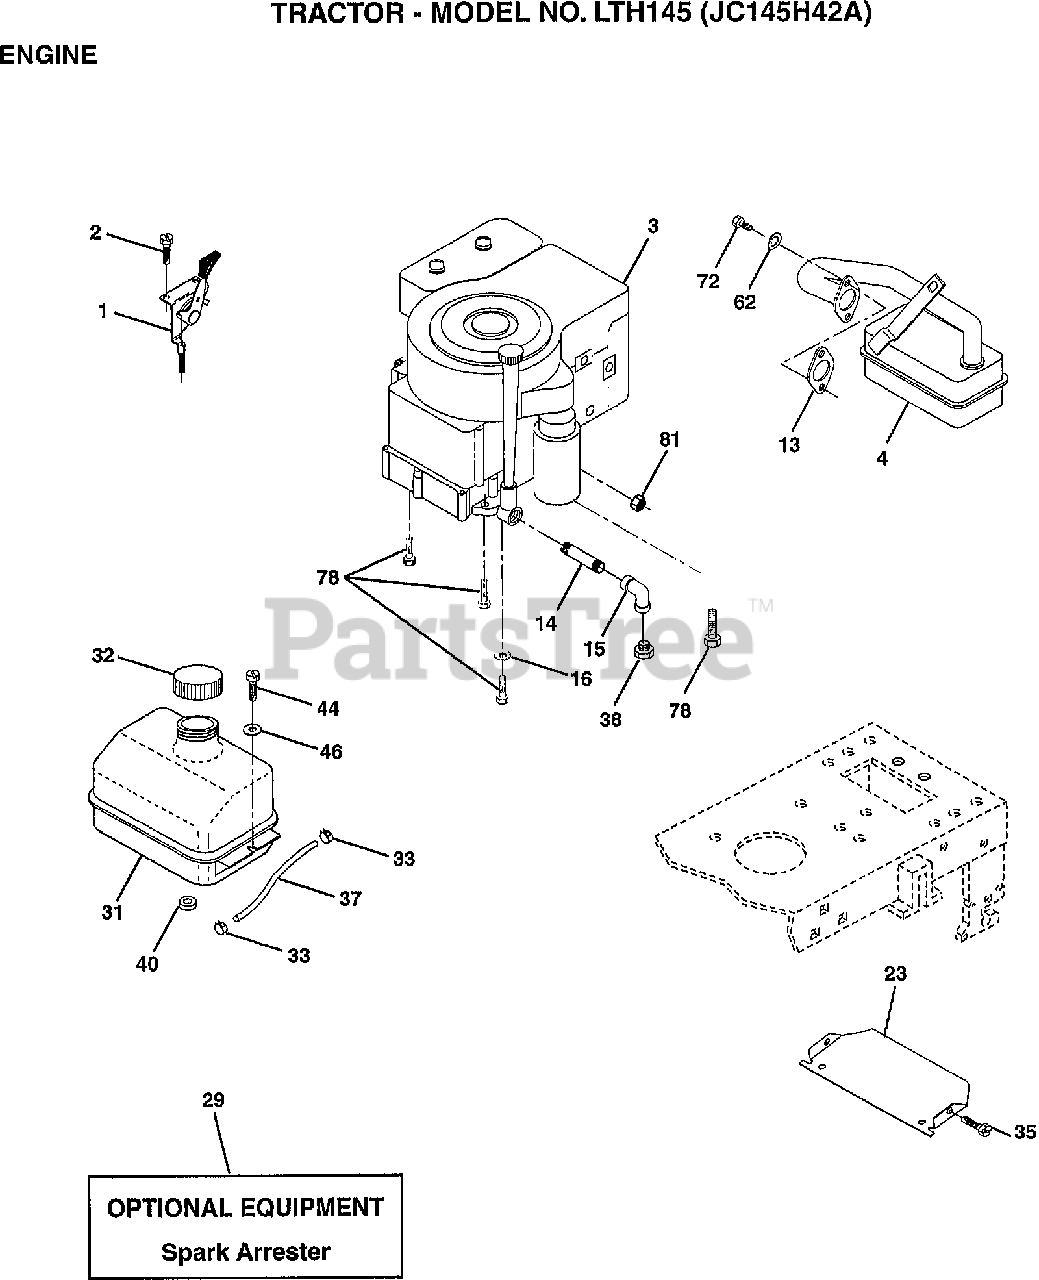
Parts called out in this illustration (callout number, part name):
2	SCREW HEX THD CUT 1/4-20X5/8 T
14	NIPPLE PIPE 3/8 NPT X 3"
15	ELBOW STD 90 DEGREE 3/8-18 NPT
16	WASHER LOCK
29	KIT.ARREST.SPARK (392-390)
35	SCREW THDROL 5/16-18 X 3/4 TYT
44	SCREW HEXWSH THDROL 1/4-20X3/4
46	WASHER 9/32 X 7/8 X 16 GA
72	SCREW HEXHD CAP 5/16-18X3/4
78	SCREW THDROL 3/8-16 X 1-1/4 TYTT
